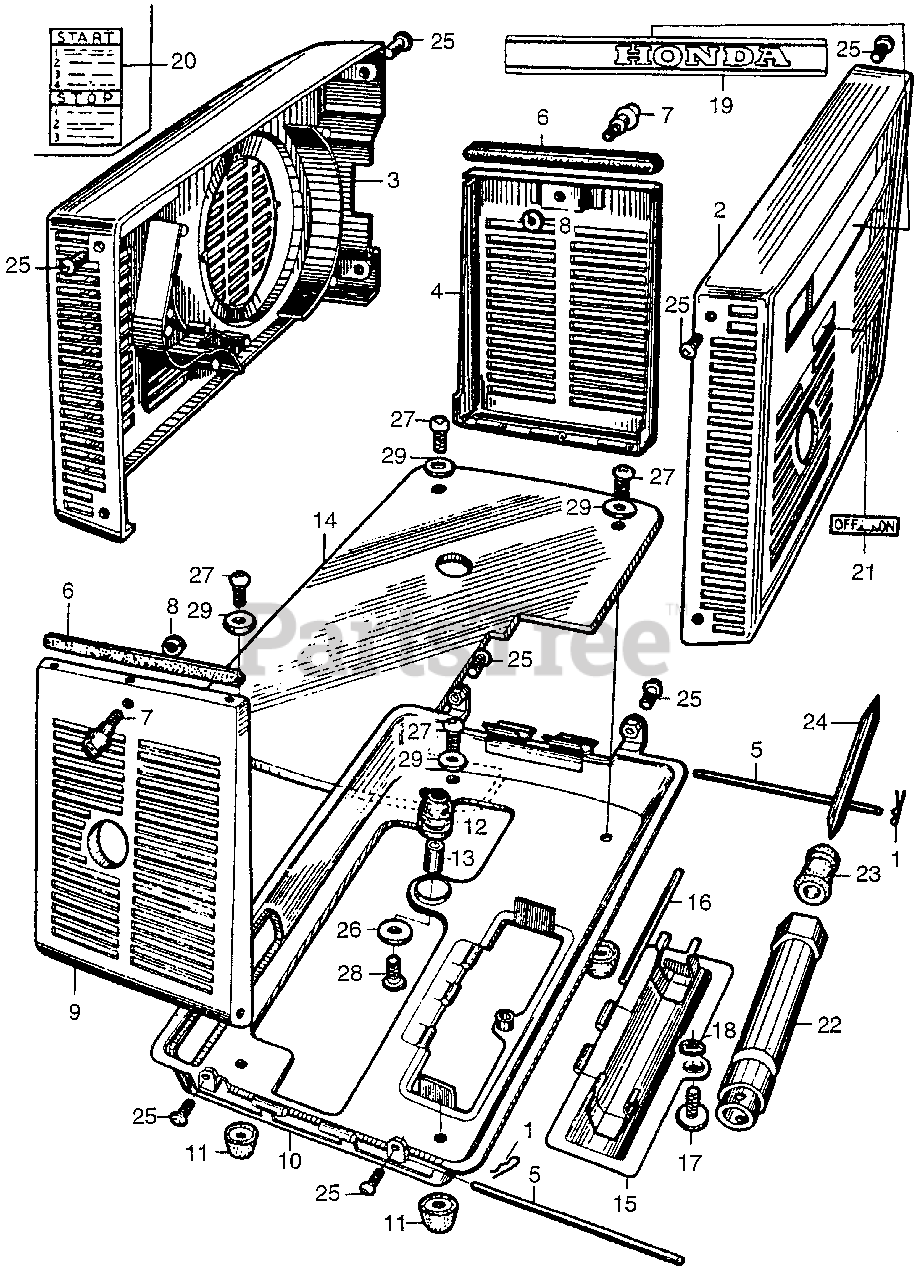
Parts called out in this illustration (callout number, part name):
1	PIN, SNAP (3MM) (NOT AVAILABLE)
2	COVER A, SIDE (NOT AVAILABLE)
3	COVER B, SIDE (NOT AVAILABLE)
4	PLATE A, SIDE *NH2M* (METALLIC SILVER) (NOT AVAILABLE)
5	SHAFT, SIDE PLATE HINGE (NOT AVAILABLE)
6	RUBBER, TANK SEAL (NOT AVAILABLE)
7	LATCH, SIDE PLATE (NOT AVAILABLE)
8	STOPPER, LATCH (NOT AVAILABLE)
9	PLATE B, SIDE (NOT AVAILABLE)
10	PLATE (LOWER) (NOT AVAILABLE)
11	RUBBER (LOWER) (NOT AVAILABLE)
12	RUBBER, PLATE SETTING (LOWER) (NOT AVAILABLE)
13	COLLAR, PLATE SETTING (LOWER) (NOT AVAILABLE)
14	PLATE, SEPARATE (NOT AVAILABLE)
15	COVER, TOOL (NOT AVAILABLE)
16	SHAFT, TOOL COVER (NOT AVAILABLE)
17	BOLT, TOOL COVER HINGE (NOT AVAILABLE)
18	O-RING (3.6X1.4) (NOT AVAILABLE)
19	MARK, TOP (NOT AVAILABLE)
20	PLATE, CAUTION (NOT AVAILABLE)
21	MARK, VALVE LEVER (NOT AVAILABLE)
22	WRENCH, PLUG (NOT AVAILABLE)
23	RUBBER, FRICTION (NOT AVAILABLE)
24	SCREWDRIVER (NOT AVAILABLE)
25	SCREW, SIDE COVER SETTING (NOT AVAILABLE)
26	WASHER, STOPPER
27	SCREW, PAN (4X8)
28	SCREW, PAN (5X25)
29	WASHER, PLAIN (4MM)
